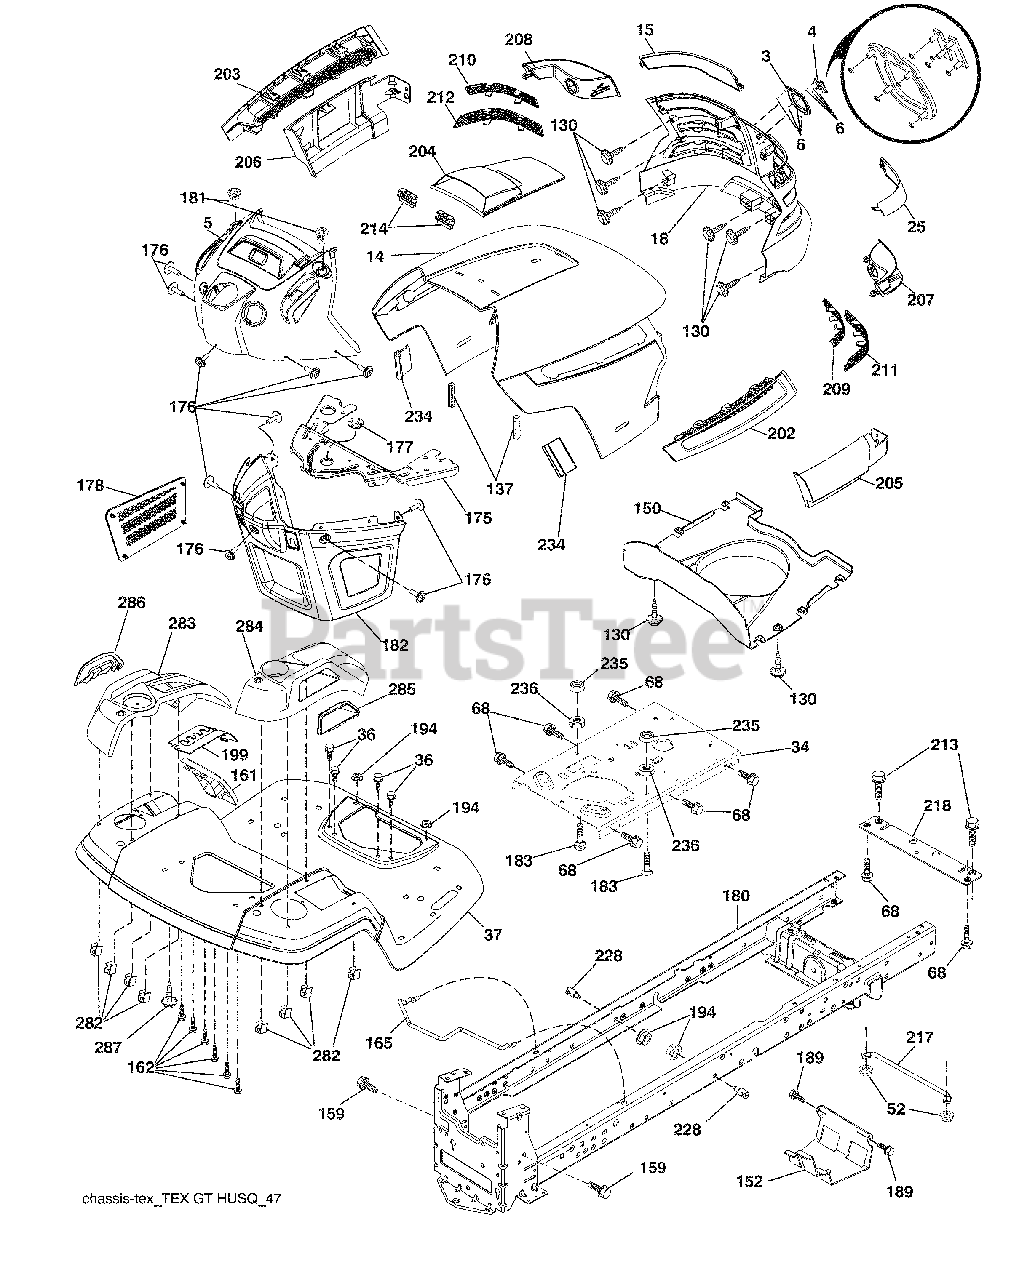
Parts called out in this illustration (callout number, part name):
3	Trim, Husq.
4	Logo
5	Dash
14	Hood
18	Grille/Lens Asm.
34	Plate Engine
36	Screw 5/16-18 x 3/4
52	Nut Lock 5/16-18
68	Screw Thdrol 5/16-18 x 1/2
130	Screw 10 x 0.750 BOS Thread
137	Bumper Dash
152	Shield Browning
159	Screw 3/8-16 x 3/4
161	Window Fuel
162	Screw 1/4 x 1/2
165	Support Tank Rear
175	Crossmember
176	Screw 10-24 x 5/8
177	Bushing Steering
178	Cargo Net Asm.
180	Chassis
181	Bushing Mtg. Fender Crgo
182	Dash Lower
183	Bolt Fin Hex 5/16-18 unc x 1-1/4
189	Screw 5/16-18 x 3/4
194	Nut Lock Hex Flange 5/16-18
199	Plate Deck Lift
202	Vent Side Hood RH
203	Vent Side Hood LH
204	Vent Top Hood
205	Skirt Hood Side RH
206	Skirt Hood Side LH
209	Insert Hex Top RH
210	Insert Hex Top LH
211	Insert Hex Bottom RH
212	Insert Hex Bottom LH
213	Bolt 5/16-18 x 3/4
214	Clip Retainer Tinner
218	X-Piece Hood Stop
228	Stud Fastener
234	Bumper Hood
235	Spacer Fender
236	Nut Lock 5/16-18 unc
282	Clip Retainer Console
283	Console Deck Lift
284	Console Shift
285	Console Insert RH
286	Console Insert LH
287	Screw 1/4-20 X 3/8
